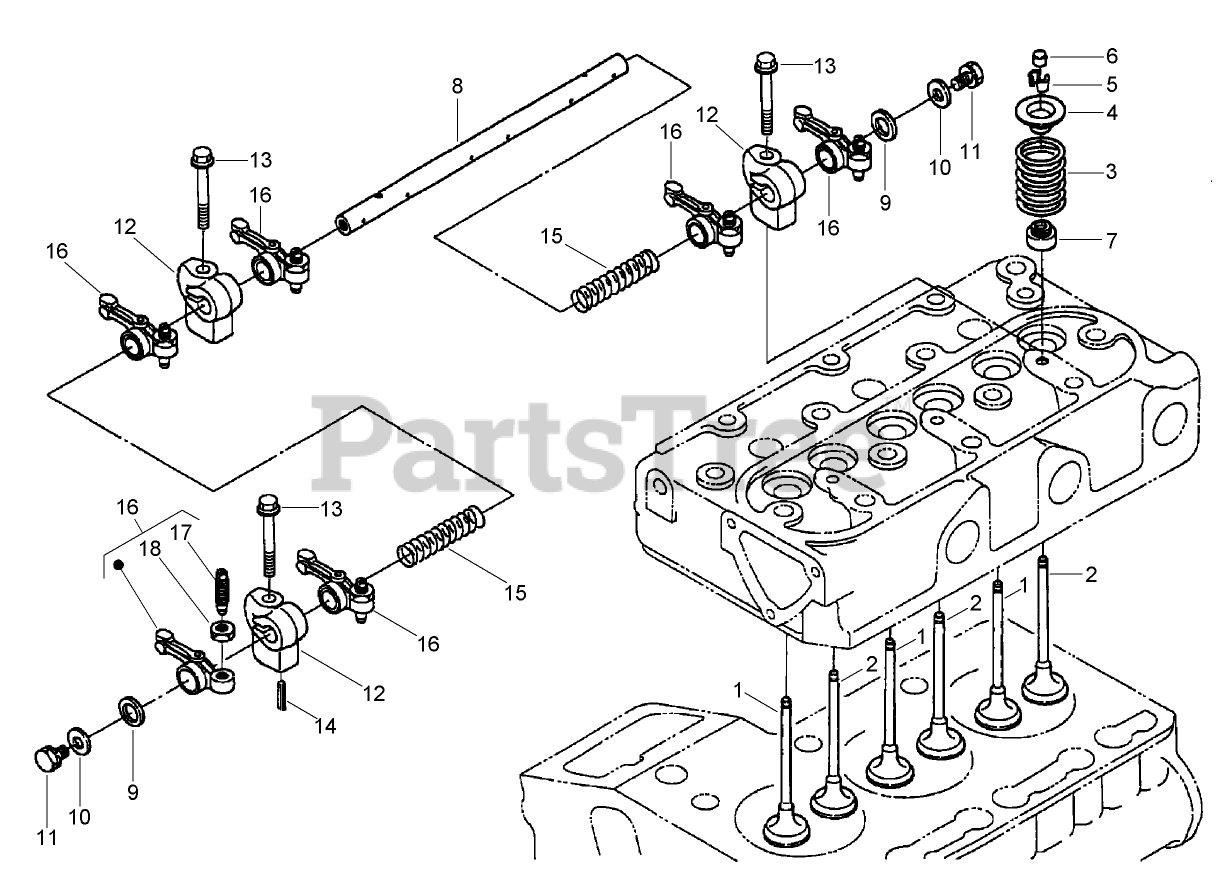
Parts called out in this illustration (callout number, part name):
1	VALVE-INLET
2	VALVE-EXHAUST
3	SPRING-VALVE
4	RETAINER-SPRING, VALVE
5	COLLET-SPRING, VALVE
6	CAP-VALVE
7	SEAL-STEM, VALVE
8	SHAFT-ARM, ROCKER
9	WASHER
10	WASHER-PLAIN
12	BRACKET-ARM, ROCKER
13	BOLT-FLANGE
14	PIN-SPRING
15	SPRING
16	ROCKER ARM ASM
17	SCREW-ADJUSTING
